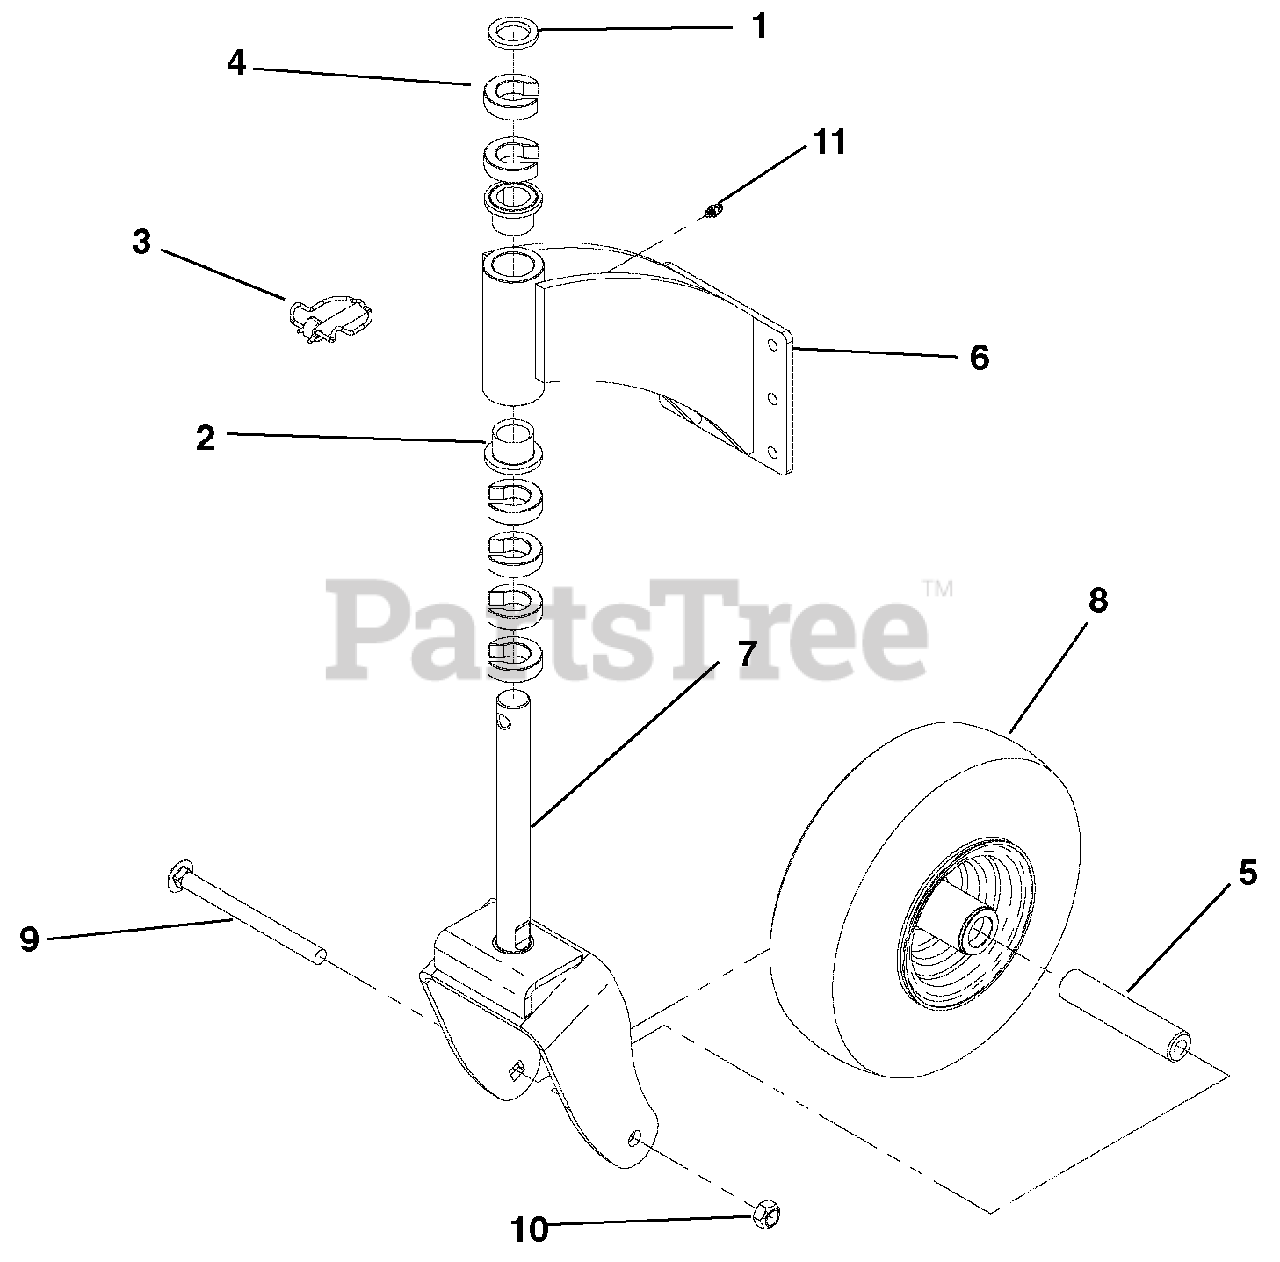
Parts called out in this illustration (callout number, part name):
1	Bushing, 1.03 x 1.50 x .179
2	Bearing, Flange 1.00 x 1.25 x 1.00
3	Pin, Lock .438 x 2.00
4	C-Spacer, 1.00 x 1.77 x .50
5	Tube, 1.00 x .50 x 4.76
6	Weldment, Caster Mount Bracket
7	Weldment, Front Wheel Fork
8	Wheel, Front 11 x 4 x 5
9	Bolt, .50-13 x 6.00 Round Head Square Neck
10	Locknut, .50-13 Crown
11	Grease Zerk, .25-28 Straight .69 LG
